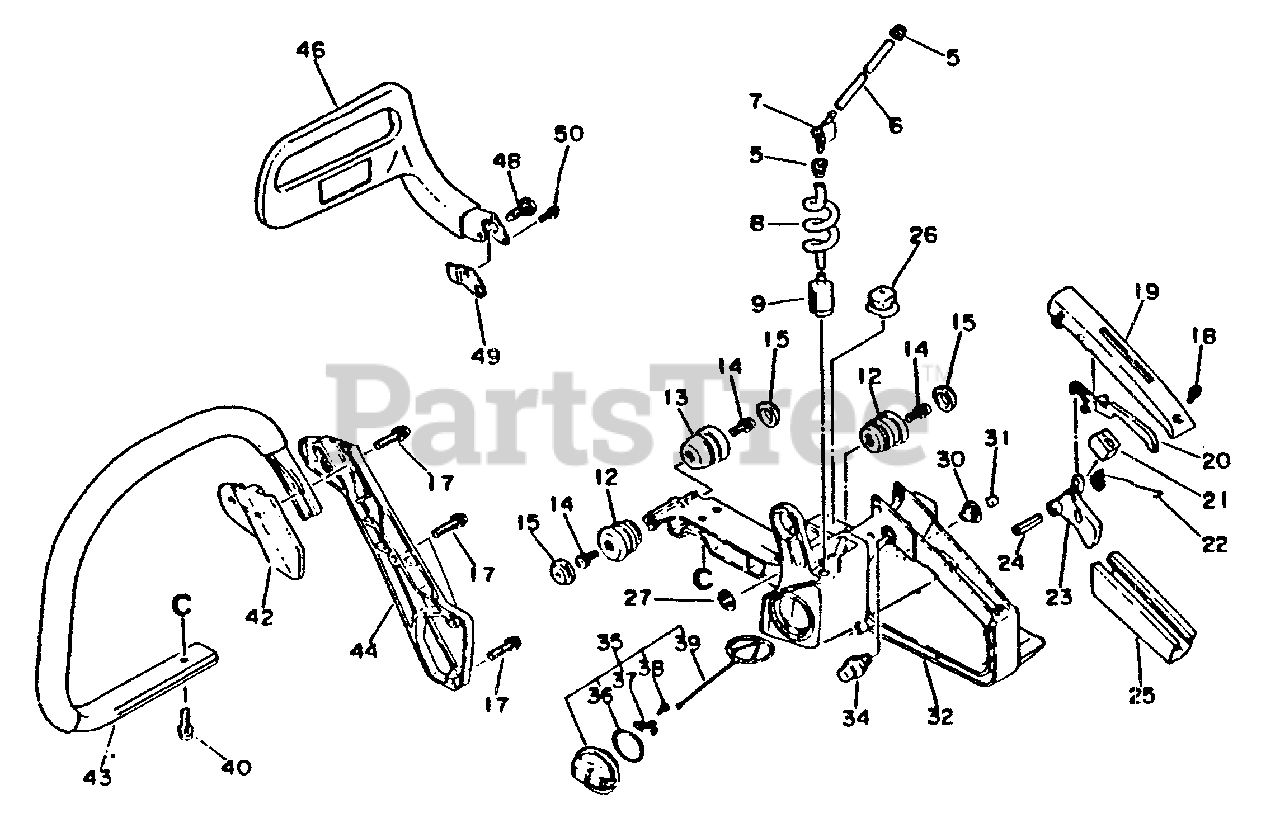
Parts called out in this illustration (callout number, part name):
5	GROMMET
6	PIPE, FUEL - 3×6×100
7	CONNECTOR, PIPE
8	PIPE - SPIRAL
9	FILTER, FUEL
12	CUSHION
13	CUSHION
14	SCREW - 5×10
15	CAP, CUSHION
17	SCREW - 5×20
18	SCREW - 4×14
19	GRIP, REAR HANDLE
20	CONTROL, THROTTLE
21	CUSHION
22	SPRING, THROTTLE RETURN
23	TRIGGER, THROTTLE - BLACK
24	PIN, SPRING 5×25
25	GRIP, HANDLE
27	CUSHION (B)
30	VENT ASSY
31	FILTER, CHECK VALVE
32	HANDLE - REAR
34	LATCH, THROTTLE
35	CAP ASSY
36	O-RING 29
37	RETAINER, CONNECTOR
38	SCREW 3×8
39	CONNECTOR, CAP L= 60 MM
40	SCREW - 5×14
42	BRACKET, HANDLE - INNER
43	HANDLE, FRONT
44	BRACKET, HANDLE - OUTER
50	SCREW - 4×10
